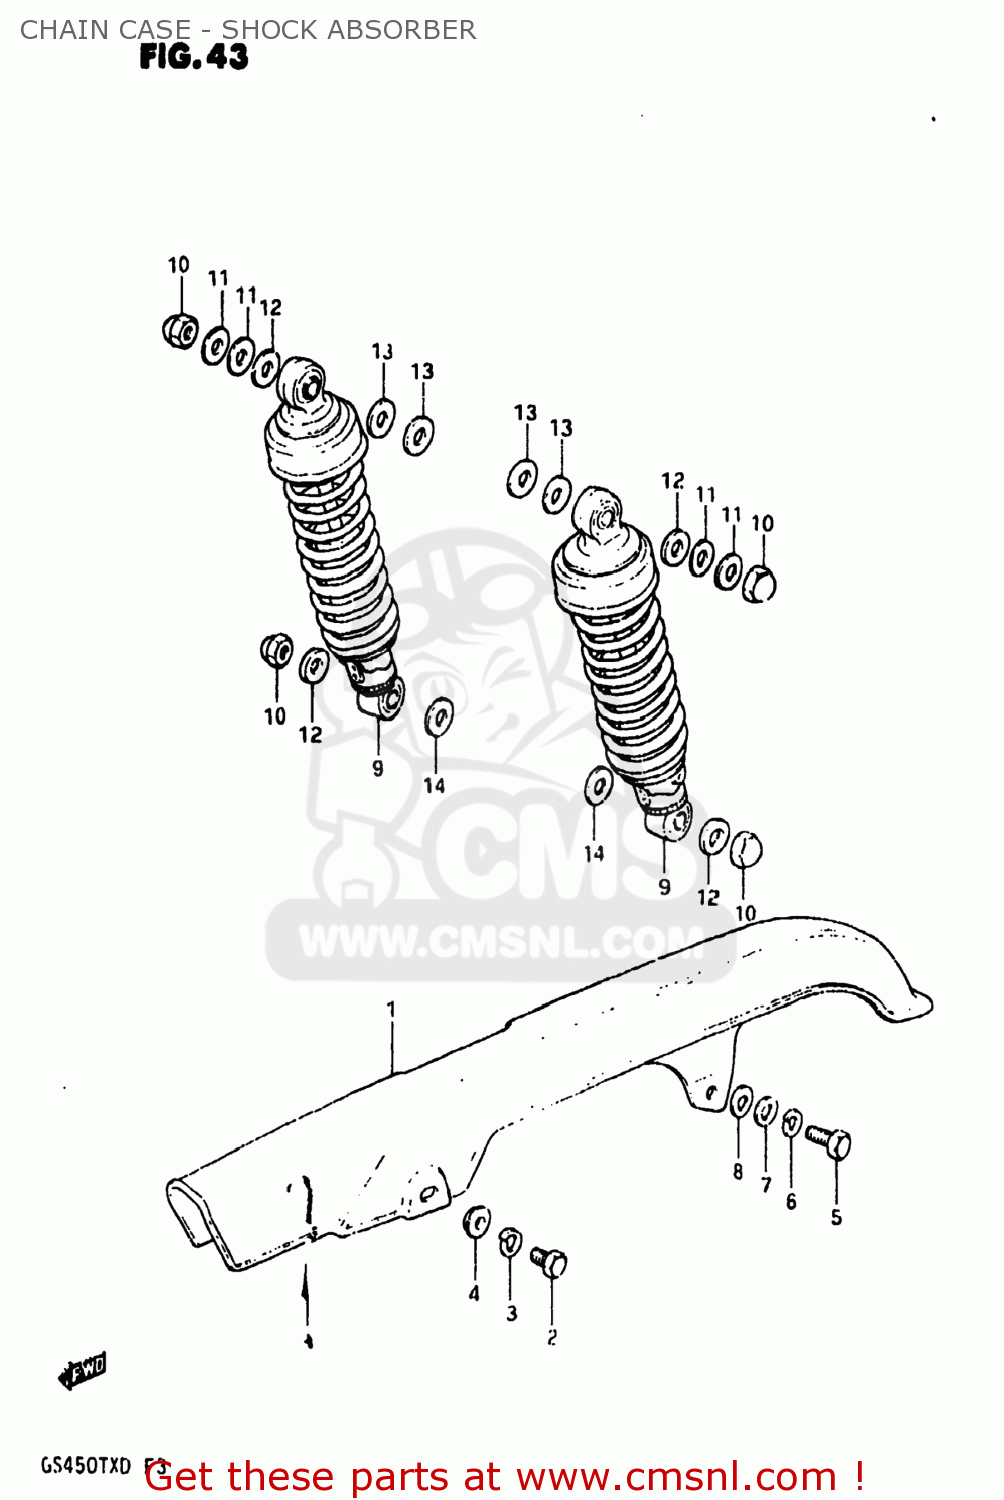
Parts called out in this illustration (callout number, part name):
1	CASE,CHAIN
2	BOLT
3	LOCK WASHER
4	WASHER,LOCK
5	BOLT
6	LOCK WASHER
7	WASHER
8	WASHER(6.5X18X1)
9	ABSORBER ASSEMBLY,REAR SHOCK
10	NUT, LOWER LH
11	WASHER(10.5X24X3.2)
12	WASHER
13	WASHER
14	WASHER (12.5X24X1.6)
